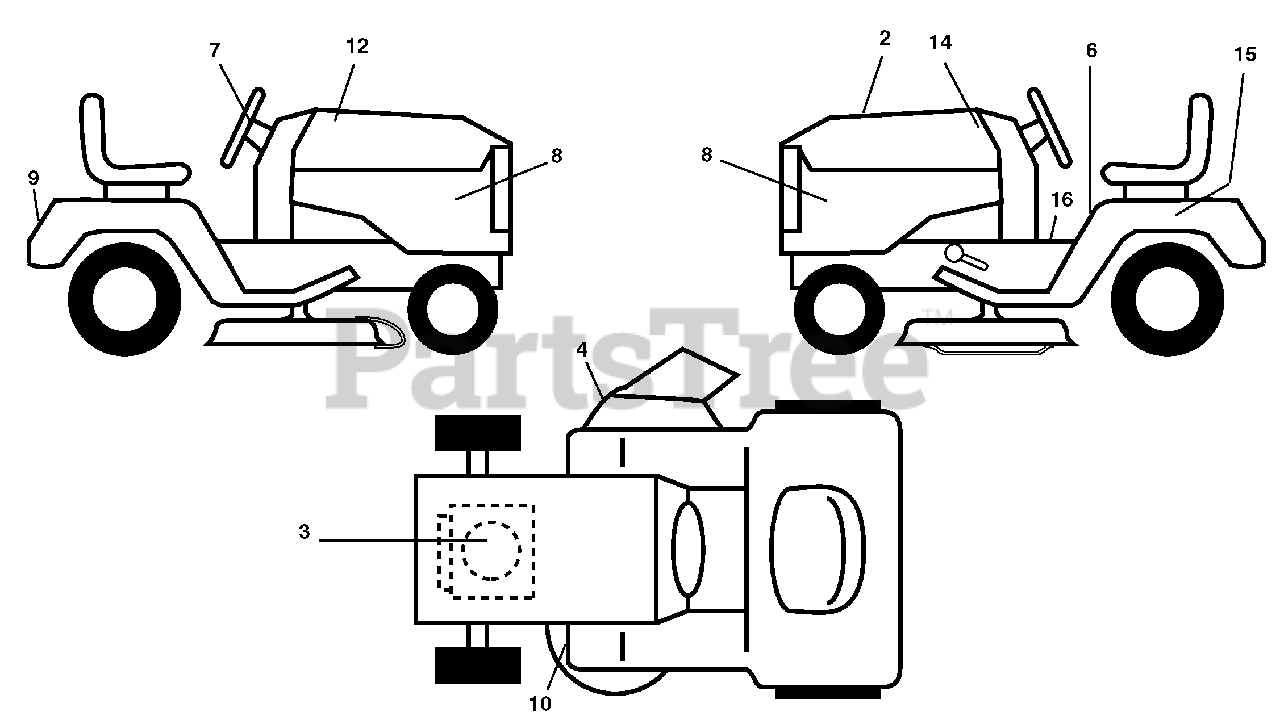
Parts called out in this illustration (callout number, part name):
2	Decal, Replacement
3	Decal, Engine HP
4	Decal Warning
6	Decal, Fender Danger English
7	Decal Ins Str Wh
8	Decal, Side Panel
9	Decal, Fender
10	Decal, V-Belt Sch.
12	Decal, Hood RH
14	Decal, Hood LH
15	Decal, Caution, Battery
16	Decal, Oper
16	Decal, Handle Lft Height Adj.
16	Manual, Operator's (E&F)
16	Manual, Parts (E&F)
